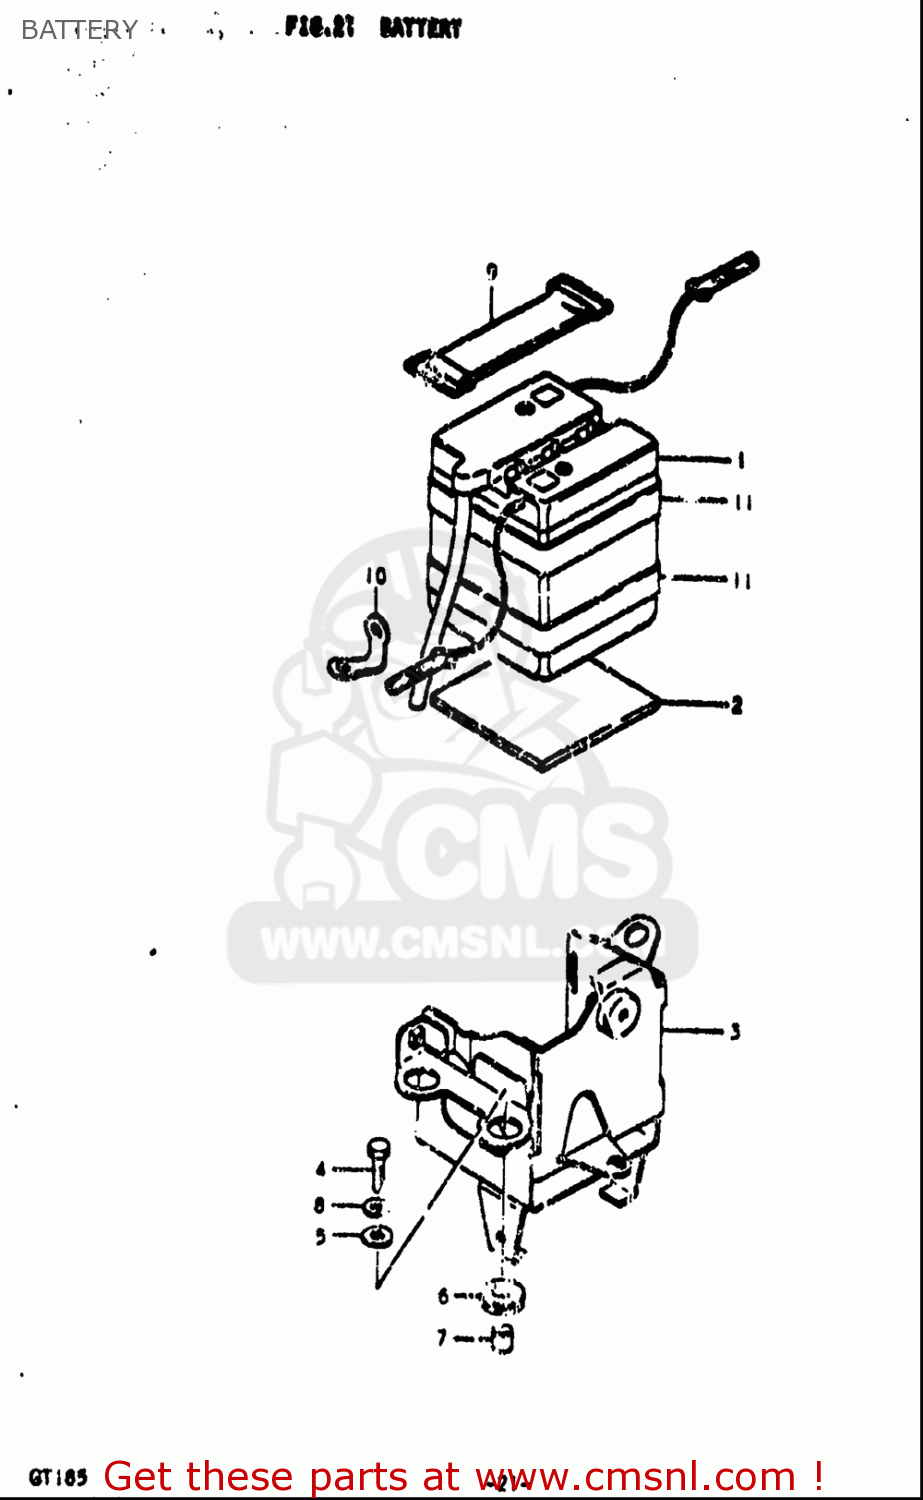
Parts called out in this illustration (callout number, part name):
1	BATTERY ASSY(6N4-2A4.2AH)
4	BOLT
5	WASHER(6.5X20X1.2)
6	CUSHION
7	SPACER,6.5X9X7
8	WASHER,LOCK
9	BAND
10	CLAMP
11	PROTECTOR,BATTERY
